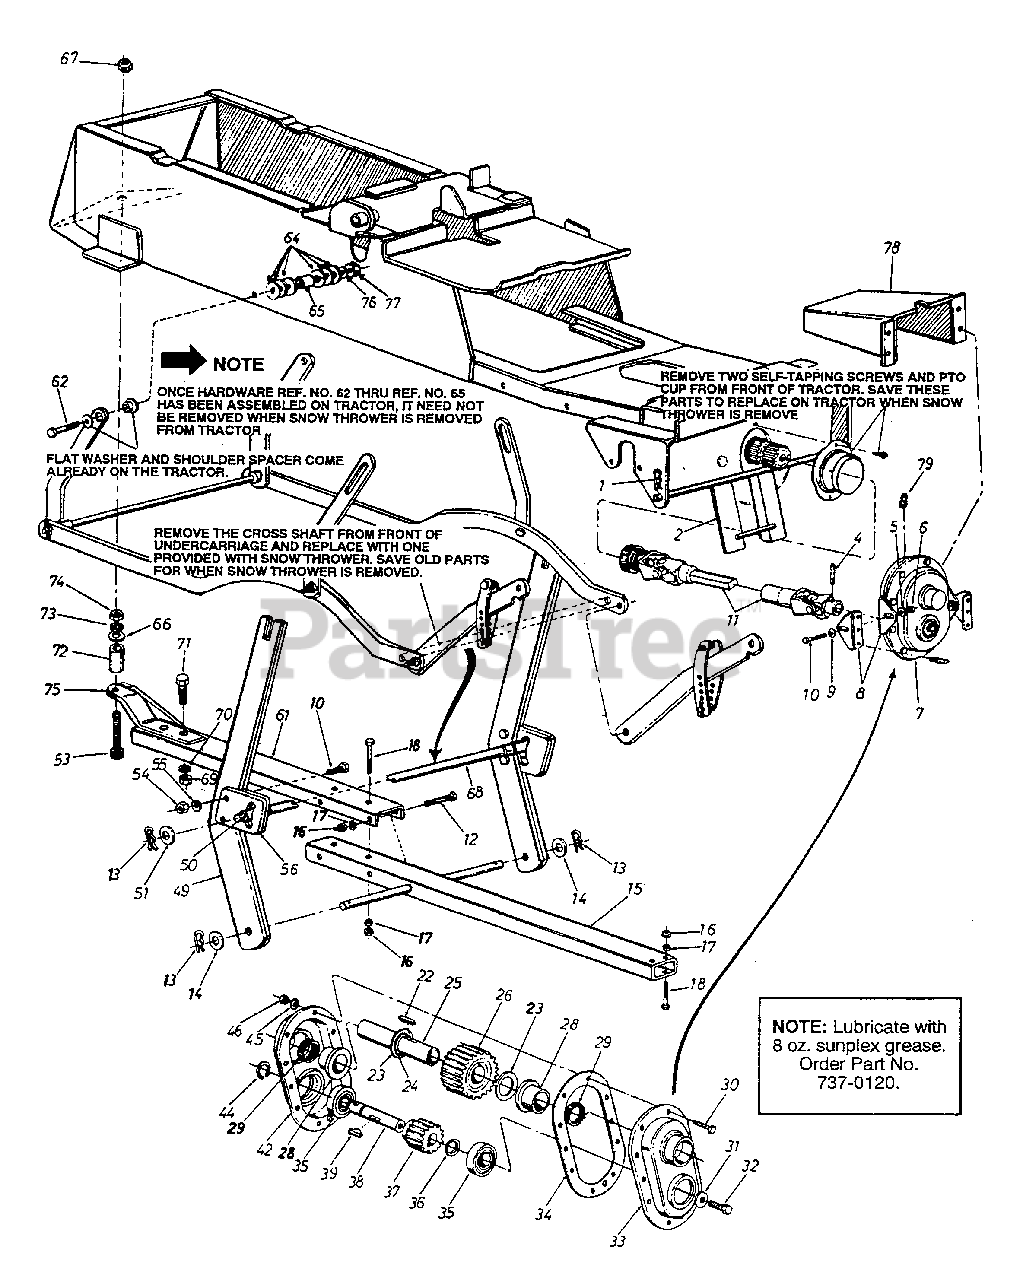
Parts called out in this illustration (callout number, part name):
1	Intern. Cotter Pin 3/4" Dia.
2	Guide Bracket Ass'y.
4	Spring Pin Spiral 5/16" Dia. x 2.5" Lg.
5	Bell-Wash. .341" I.D. x .88" O.D.
6	Hex Nut 5/16-18 Thd.
7	Gear Box Ass'y. Comp.
8	Gear Box Support Brkt.
9	Bell-Wash. .341" I.D. x .88" O.d.
10	Hex Scr. 5/26-18 x .75" Lg.
11	Universal Drive Shaft Ass'y.
12	Hex Scr. 3/8-24 x 4.50" Lg.
13	Hairpin Cotter
14	Fl-Wash. .62" I.D. x 1.12" O.D.
15	Lift Shaft Ass'y.
16	Hex Ins. Jam L-Nut 3/8-24 Thd.
17	L-Wash. 3/8" Scr.
18	Hex Scr. 3/8-24 x 2.75" Lg.
22	Fl-Wash. 1.31" I.D. x 2.00" O.D. x .060
24	Snap Ring For 1/25" Dia. Shaft
25	Gear Shaft 1.25" Dia. x 6.0" Lg.
26	28 Teeth Spur Gear
28	Flange Brg. 1.25" I.D. x 1.75" O.D.
29	Oil Seal 1.25" I.D. x 1.75" O.D. x .26
30	Hex Scr. 1/4-28 x .88" Lg.
31	Fl-Wash. .40" I.D. x 1.25" O.D. x .160
32	Hex L-Scr. 3/8-24 x 1.00" Lg.
33	Compl. Gear Hsg. Half - L.H.
34	Gasket
35	Ball Brg. 1.00" I.D. x 2.00" O.D.
36	Fl-Wash. 1.03" I.D. x 1.63" x .090
37	15 Teeth Spur Gear
38	Input Shaft
39	Woodruff Key 1/4" x 3/4" Dia.
42	Compl. Gear Hsg. Half - R.H.
44	Snap Ring for 1.00" Dia. Shaft
45	Spring Wash. 1/4" I.D.
46	Hex Nut 1/4-28 Thd.
51	Fl-Wash. .62" I.D. x 1.12" O.D.
53	Hex Bolt 5/8-18 x 4.00" Lg.
54	Hex Nut 5/16-18 Thd.
55	L-Wash. 5/16" Scr.
61	Lift Bracket
62	Hex Scr. 3/8-24 x 2.50"
64	Fl-Wash. .375" I.D. x 1.00" O.D. x .135"
65	Spacer .275" I.D. x .625" O.D x .440
66	Fl-Wash. .62" I.D. x 1.12" O.D.
67	Hex Jam L-Nut 5/8-18 Thd.
68	Cross Shaft Ass'y.
69	Hex Nut 1/2-13 Thd.
70	L-Wash. 1/2" Scr.
71	Hex Scr. 1/2-13 x 1.25"
72	Bushing
73	L-Wash. 5/8" Scr.
74	Hex Jam Nut 5/8-18 Thd.
77	Hex Nut 3/8-24 Thd.
78	Drive Shaft Cover
79	Grease Fitting
